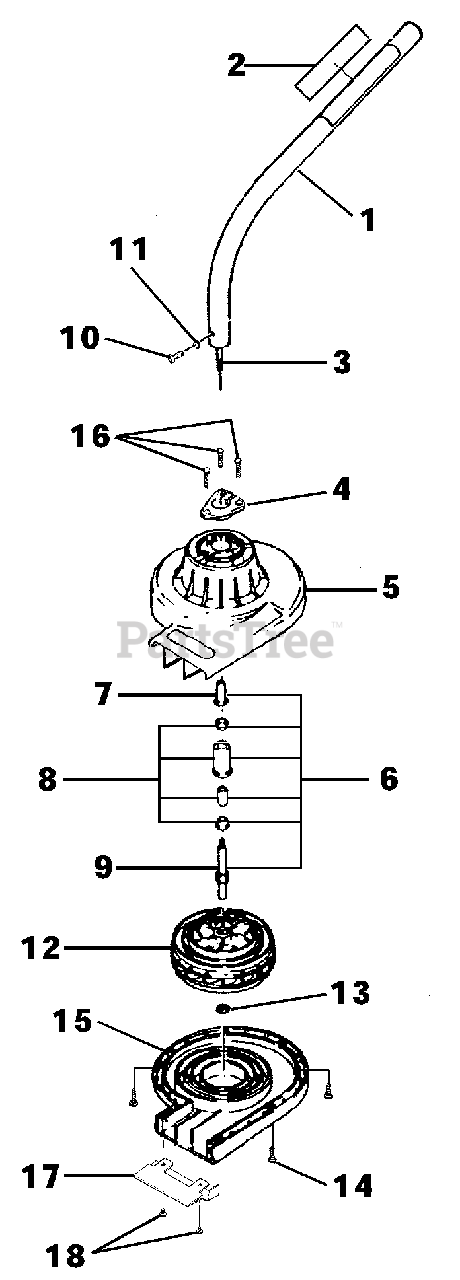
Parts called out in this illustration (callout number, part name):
1	DRIVESHAFT HOUSING
2	DECAL-Warning
3	CABLE-Flex
4	CLAMP
5	UPPER HOUSING
6	BEARING HOUSING
7	ADAPTER-Arbor
9	SHAFT-Arbor
10	SCREW (10-24 x .312")
11	WASHER, Lock (#10)
12	IMPELLER
13	Clip
14	SCREW, Pan Hd. (8-16 x .750)
15	LOWER HOUSING
16	SCREW-Thread Forming (8-16 x 1")
17	GUARD-Lower Housing
18	SCREW (10-16 x 1/4")
